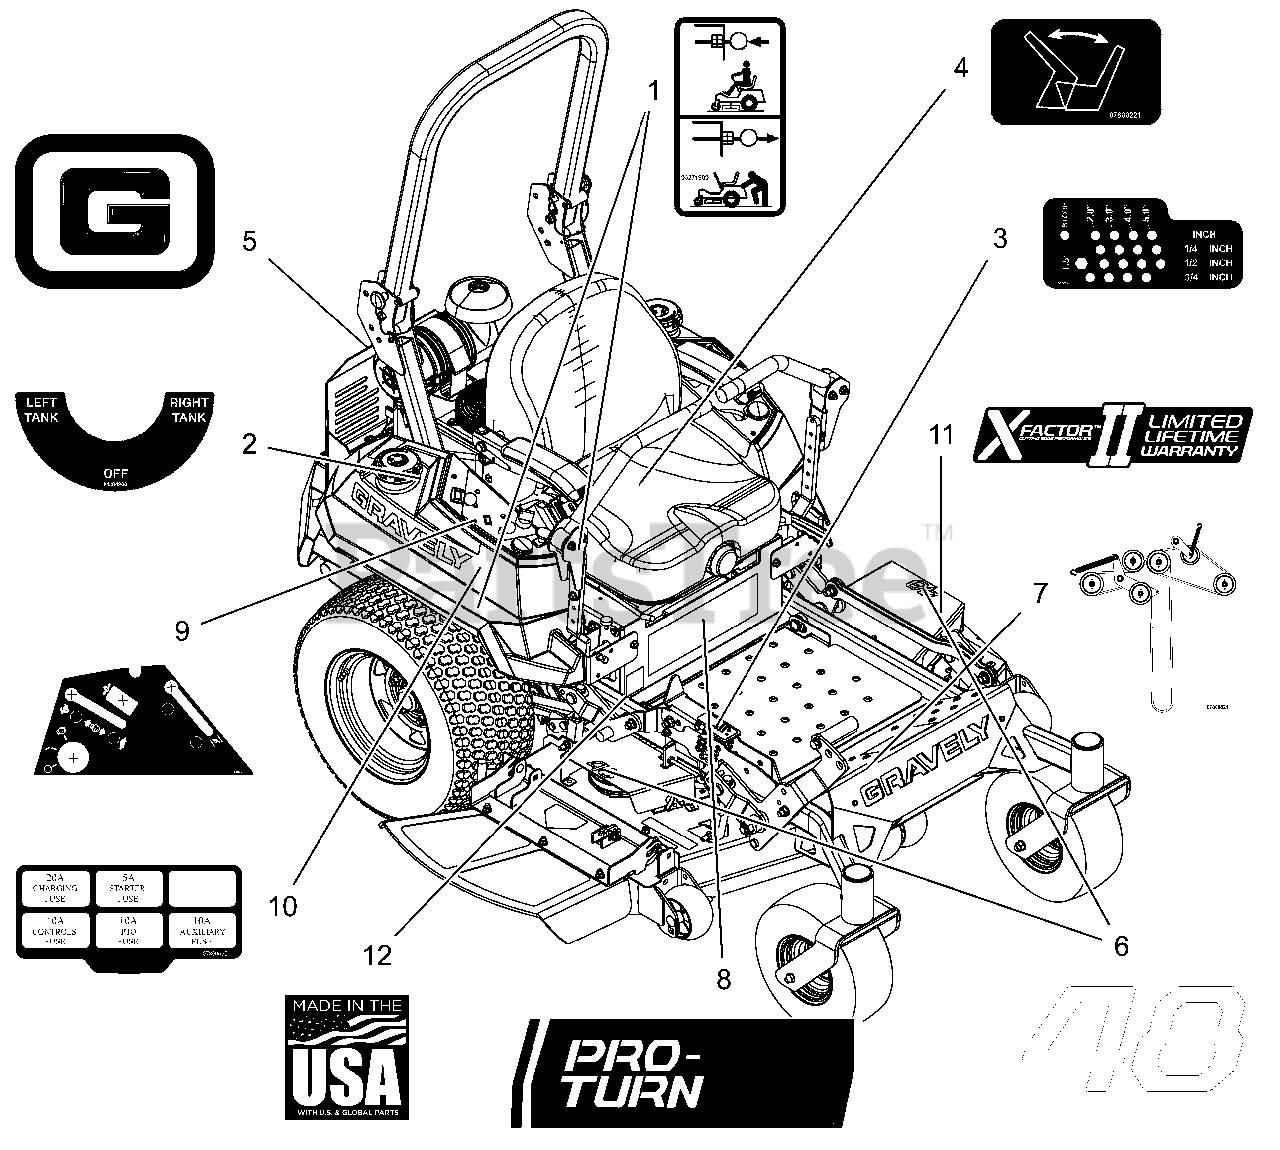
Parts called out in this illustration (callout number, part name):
1	DECAL, TRANSMISSION DISCONNECT
2	DECAL, FUEL VALVE
3	DECAL, HEIGHT OF CUT
4	DECAL - SEAT RELEASE
5	DECAL, GRAVELY BRAND
6	DECAL, 48"
7	DCL,BELT ROUTE-RH V-SIDE IDLER
8	DECAL, PRO-TURN 148
9	DECAL, NON-EFI CONTROL PANEL
10	DECAL, FUSE BLOCK
11	DECAL, X-FACTOR DECK
12	DECAL, MADE IN USA
